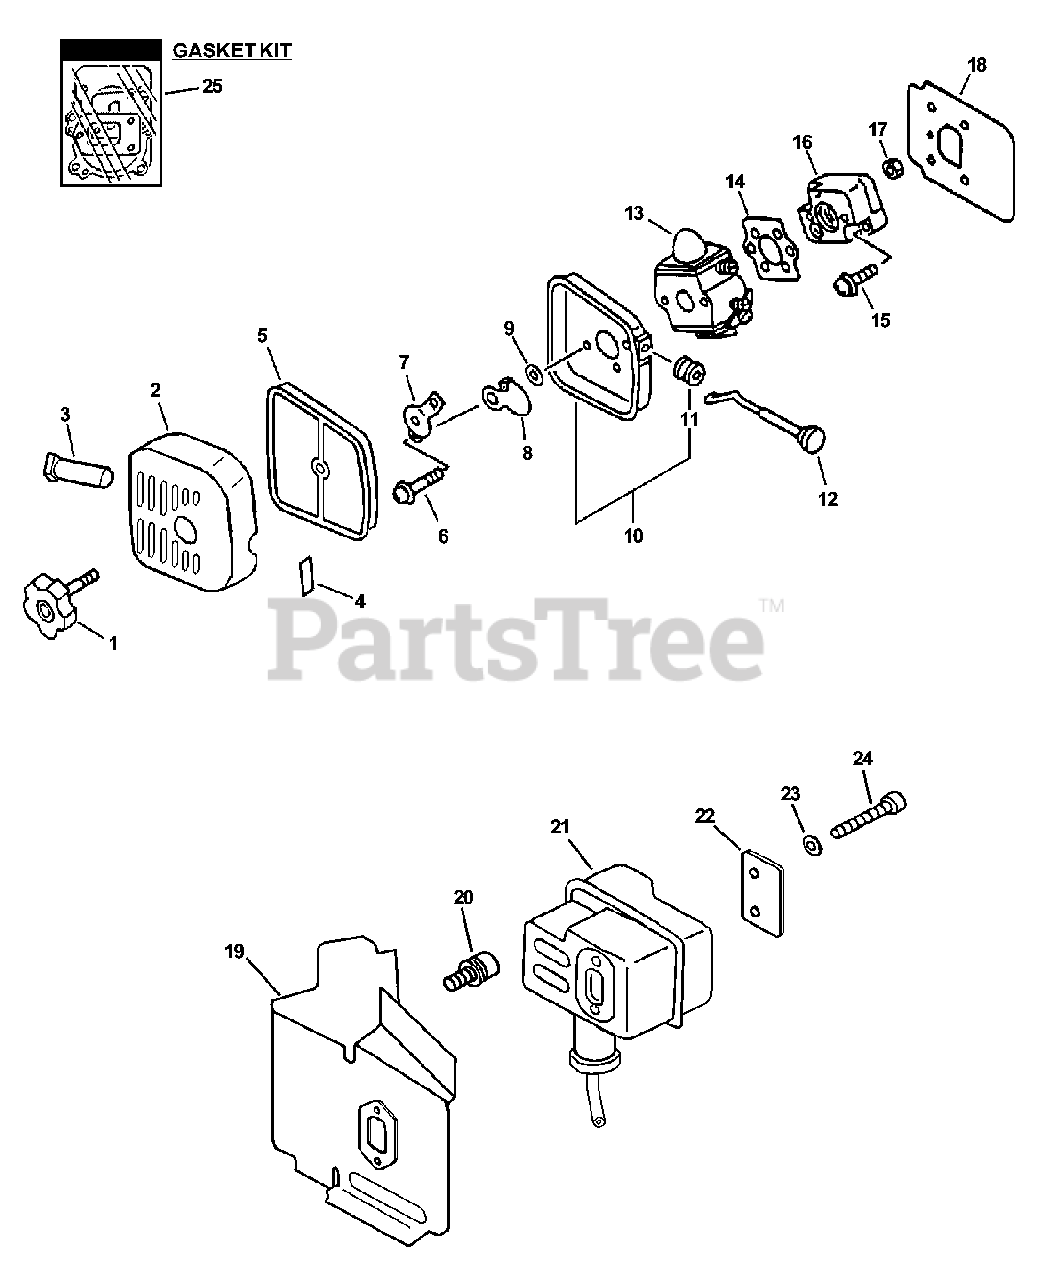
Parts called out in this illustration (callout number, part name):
1	THUMBSCREW
2	COVER, AIR FILTER
4	LABEL, CHOKE
5	FILTER, HEAVY-DUTY AIR
6	SCREW 5×57
7	PLATE, PREVENT
8	SHUTTER, CHOKE
9	WASHER 5.2×8×0.8T
10	CASE ASSY, AIR FILTER
11	GROMMET, CHOKE
12	ROD, CHOKE
13	CARBURETOR - C1U-K54A
14	GASKET, INTAKE
15	SCREW 5×20
16	INSULATOR, INTAKE
17	NUT M5
18	HEAT SHIELD, INTAKE
19	HEAT SHIELD, EXHAUST
20	BOLT 4×8
21	MUFFLER
22	PLATE, EYE
23	WASHER, FLAT 5.5×10×0.8
24	SCREW - 5×70
28	GASKET KIT
